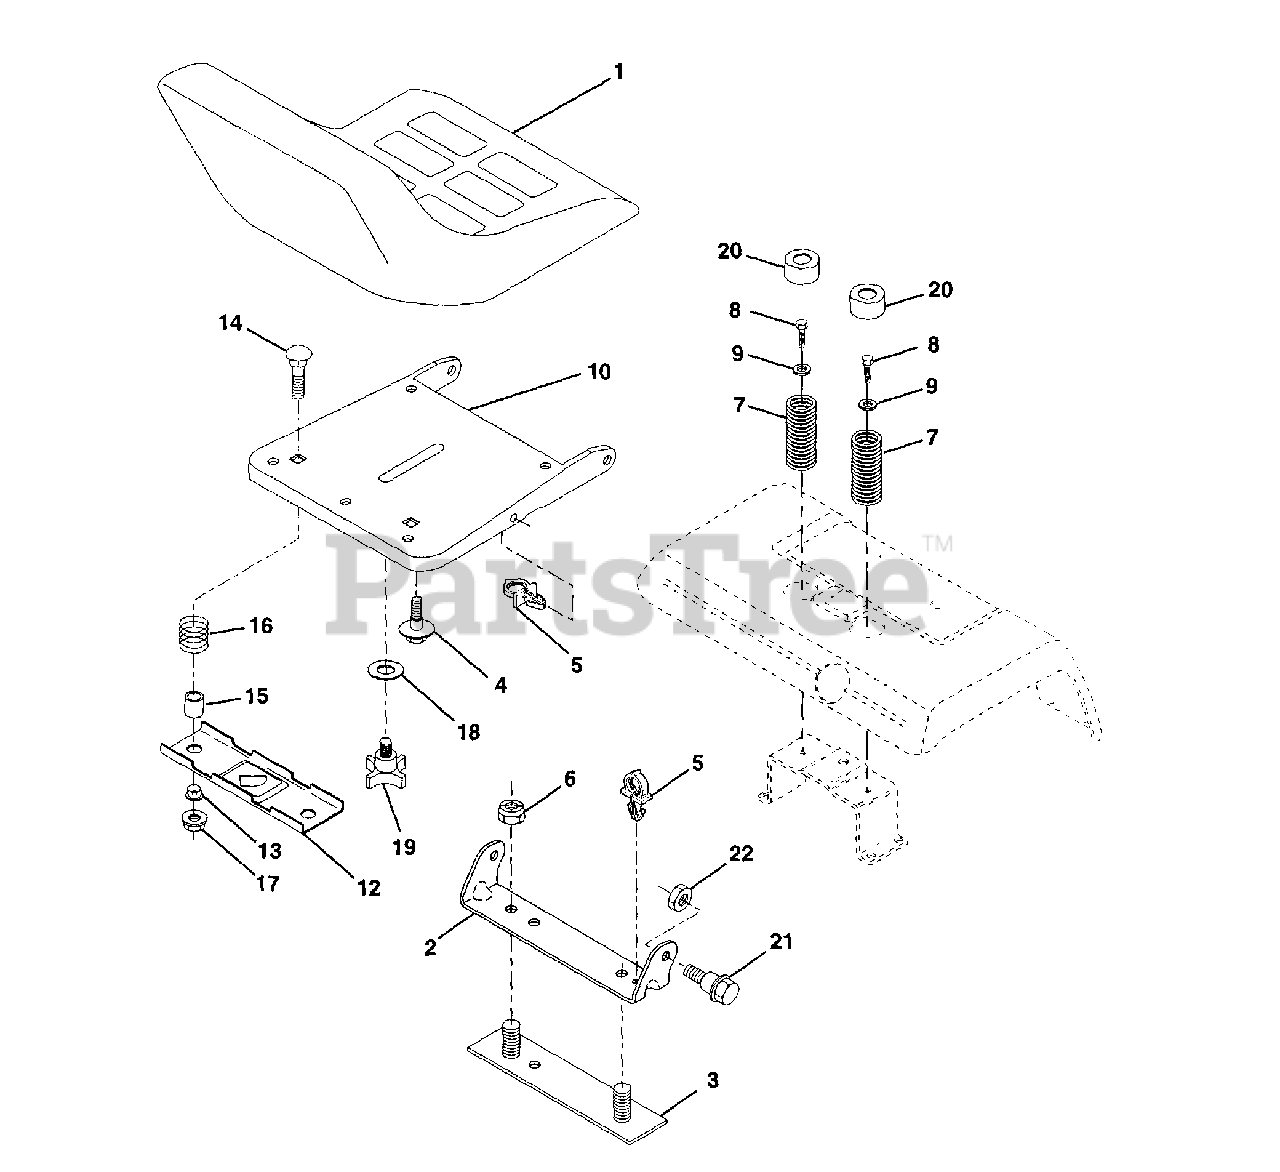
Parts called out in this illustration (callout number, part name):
1	Seat
2	Bracket, Pivot Seat
3	Strap, Fender
4	Bolt, Shoulder 5/16-18 X .62
5	Clip, Push In
6	Locknut 3/8-16 Unc
7	Spring, Seat Cprsn
8	Screw, Thdrol 5/16-18 X 1/2
9	Washer 13/32 X 1 X 14 Ga.
10	Pan, Seat
12	Bracket, Mounting Switch
13	Bushing, Snap
14	Bolt, Carriage 1/4-20 X 1-3/8
15	Spacer, Split
16	Spring, Cprsn
17	Nut, Lock 1/4 Lge Flg Gr. 5
18	Washer 17/32 X 1-3/16 X 12 Ga.
19	Knob, Seat 1/2-13 Unc
20	Cap, Spring Seat
21	Bolt, Shoulder 5/16-18 Unc
22	Nut, Crownlock 5/16-18 Unc
